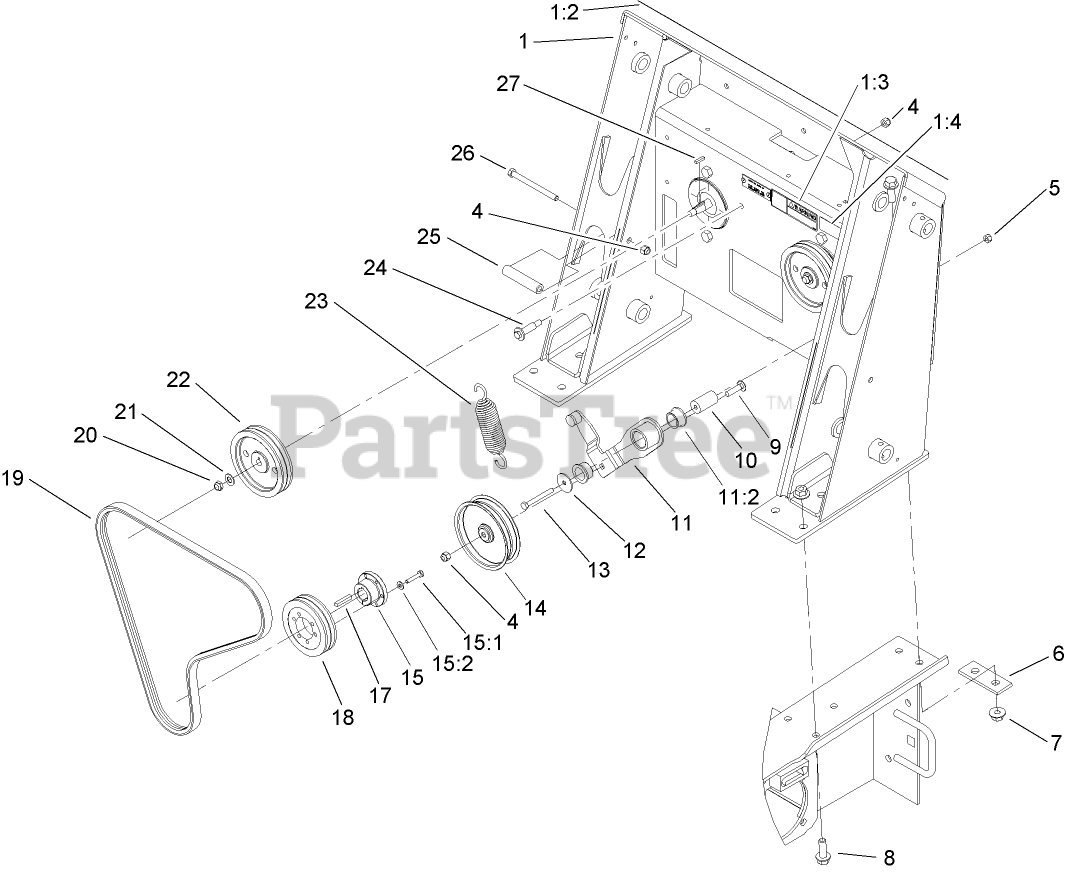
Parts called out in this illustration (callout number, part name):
1	LOADER TOWER ASM
1:2	DECAL-PANEL, CONTROL
1:3	DECAL-WARNING
1:4	DECAL-PATENT
4	NUT-LOCK, NI
5	NUT-LOCK, NI
6	PLATE-STIFFENER
7	NUT-LOCK, FLANGE
8	SCREW-HHF
9	SCREW-CARR
10	SPACER-MOUNTING
11	IDLER ARM ASM
11:2	BUSHING-FLANGE
12	WASHER-FLAT
13	SCREW-HH
14	PULLEY-IDLER
15	BUSHING
15:1	SCREW-HH
15:2	WASHER-LOCK / SP
17	KEY-SQUARE
18	PULLEY
19	V-BELT
20	NUT-LOCK, NI
21	WASHER-FLAT
22	PULLEY
23	SPRING-EXTENSION
24	BOLT-WHEEL
25	TUBE-SPACER
26	SCREW-HH
